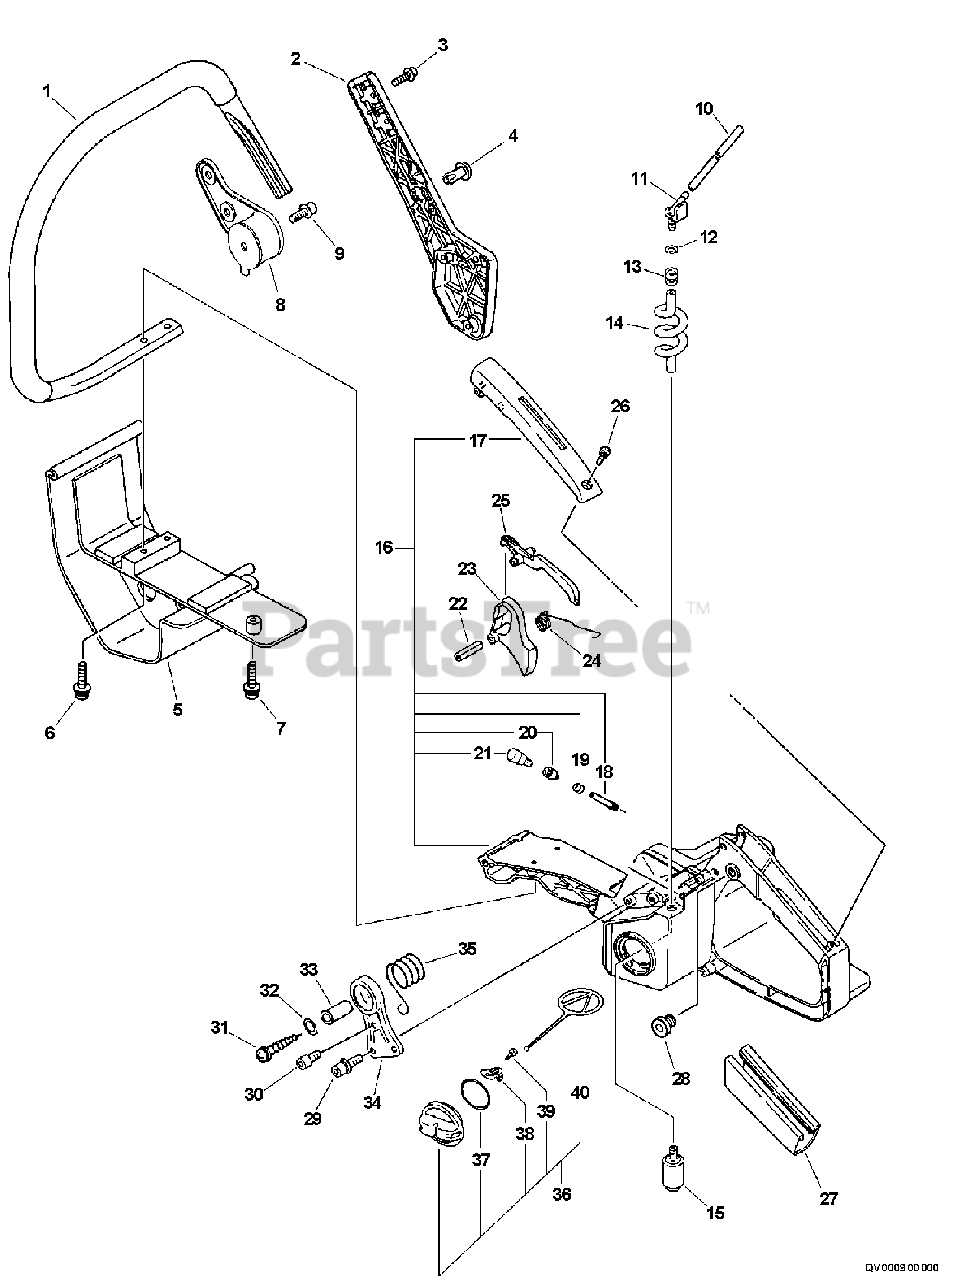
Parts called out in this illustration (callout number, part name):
1	HANDLE - FRONT
2	BRACKET, HANDLE
3	SCREW - 5X20
6	SCREW - 5X30
7	SCREW - 5X25
8	CUSHION
9	SCREW - 5X14
10	PIPE - 3X6X110 -- BLACK
11	CONNECTOR, PIPE
12	CLIP - 6.5
13	GROMMET
14	PIPE - BLACK
15	FILTER, FUEL
16	HANDLE ASSY - REAR
17	COVER, HANDLE
18	PIPE - VENT
19	CLIP - 5.5
20	COVER, VENT
21	VENT, FUEL TANK
22	PIN - SPRING -- 5X25
23	TRIGGER, THROTTLE
24	SPRING, TRIGGER
25	LEVER, TRIGGER LOCKOUT
26	SCREW - 4X14
27	GRIP, HANDLE
29	SCREW - 5X14
30	SCREW - 5X8
31	SCREW - 5X35
32	WASHER - 5
33	COLLAR - 5
34	BRACKET, CUSHION
36	CAP ASSY
37	O-RING - 29
38	RETAINER
39	SCREW - 3X8
40	CONNECTOR, CAP
